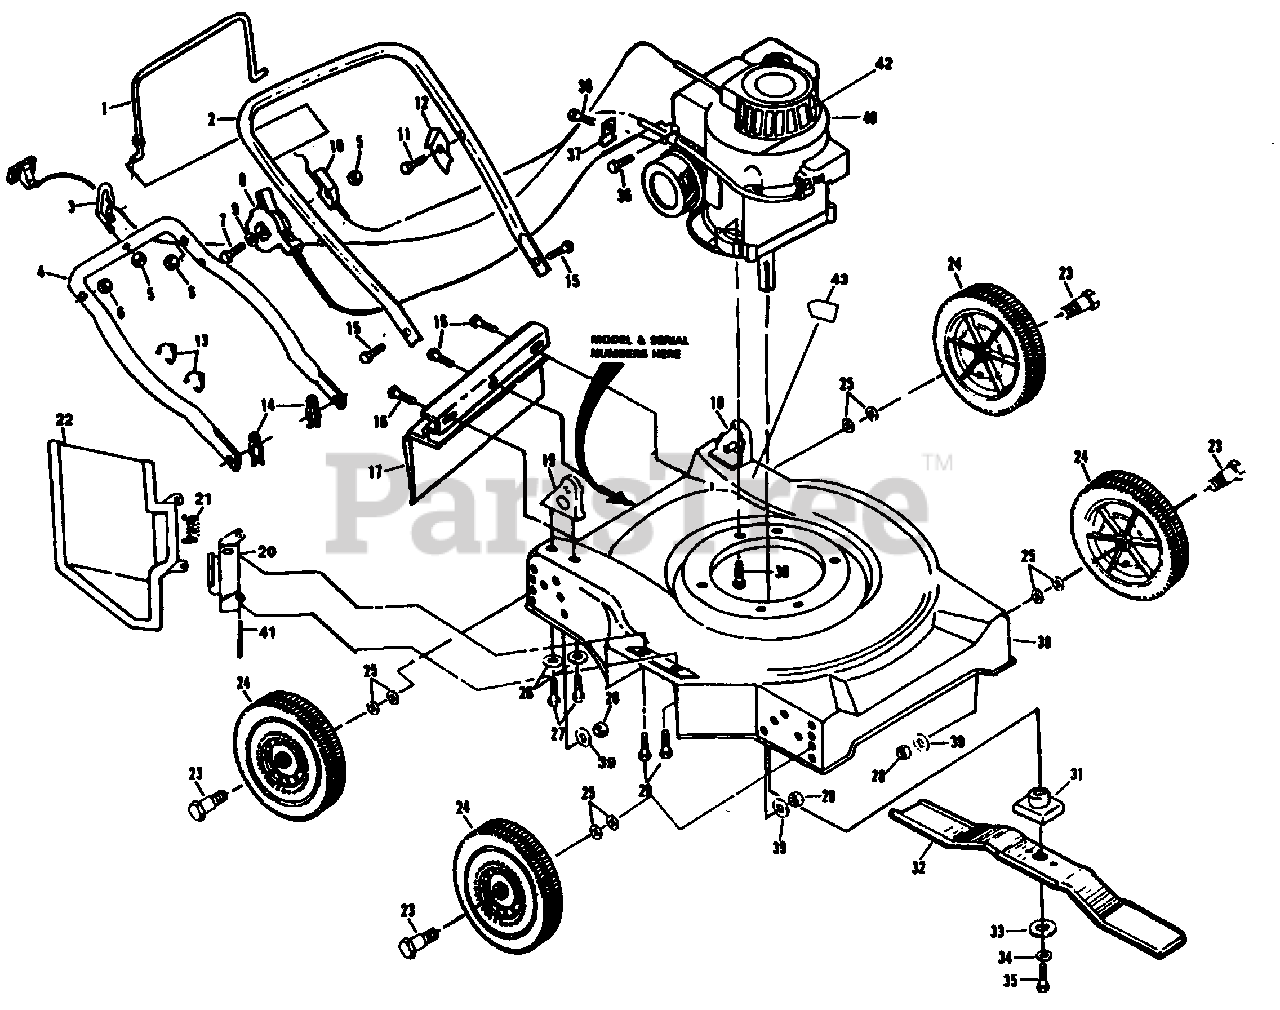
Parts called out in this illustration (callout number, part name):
1	Control Bar (AYP part number)
2	Upper Handle (AYP part number)
3	Rope Guide (AYP part number)
4	Lower Handle (AYP part number)
5	Locknut 1/4-20 (AYP part number)
6	Locknut 5/16-18 (AYP part number)
7	Machine Screw 1/4-20 x 2-1/8 (AYP part number)
8	Throttle Control, Deluxe (AYP part number)
9	Washer (AYP part number)
10	Engine Zone Control Cable
11	Hex Washer Head Screw #10-24 x 1/2 (AYP part number)
12	Up-Stop Bracket (AYP part number)
13	Cable Clip (AYP part number)
14	Hairpin Cotter (AYP part number)
15	Hex Head Bolt 5/16-18 x 1 3/4 (AYP part number)
16	Hex Washer Head Tapping Screw #10-24 x 1/2 (AYP part number)
17	Rear Deflector (AYP part number)
18	Handle Bracket Assembly (Left) (AYP part number)
19	Handle Bracket Assembly (Right) (AYP part number)
20	Housing Bracket (AYP part number)
21	Rob. Hinge (AYP part number)
22	Discharge Guard
23	Shoulder Bolt (AYP part number)
24	Wheel Assembly 7 x 1-3/4 (AYP part number)
25	Washer (AYP part number)
26	Flat Washer (AYP part number)
27	Screw 5/16-18 x 3/4 (AYP part number)
28	Locknut 3/8-16 (AYP part number)
29	Hex Head Thread Rolling w/Sems 1/4-20 (AYP part number)
30	Hex Head Thread Rolling Screw 3/8-16 x 1-1/8 (AYP part number)
31	Blade Adapter (AYP part number)
32	20" Blade
33	Hardened Washer (AYP part number)
34	Helical Lockwasher 3/8 (AYP part number)
35	Hex Head Screw 3/8-24 x 1-3/8 Grade 8
36	Screw #10 x 5/8 (AYP part number)
37	Cable Clamp (AYP part number)
38	Lawn Mower Housing
39	Washer (AYP part number)
41	Torsion Spring (AYP part number)
42	Briggs and Stratton Starter Guard (AYP part number)
43	Danger Decal (AYP part number)
